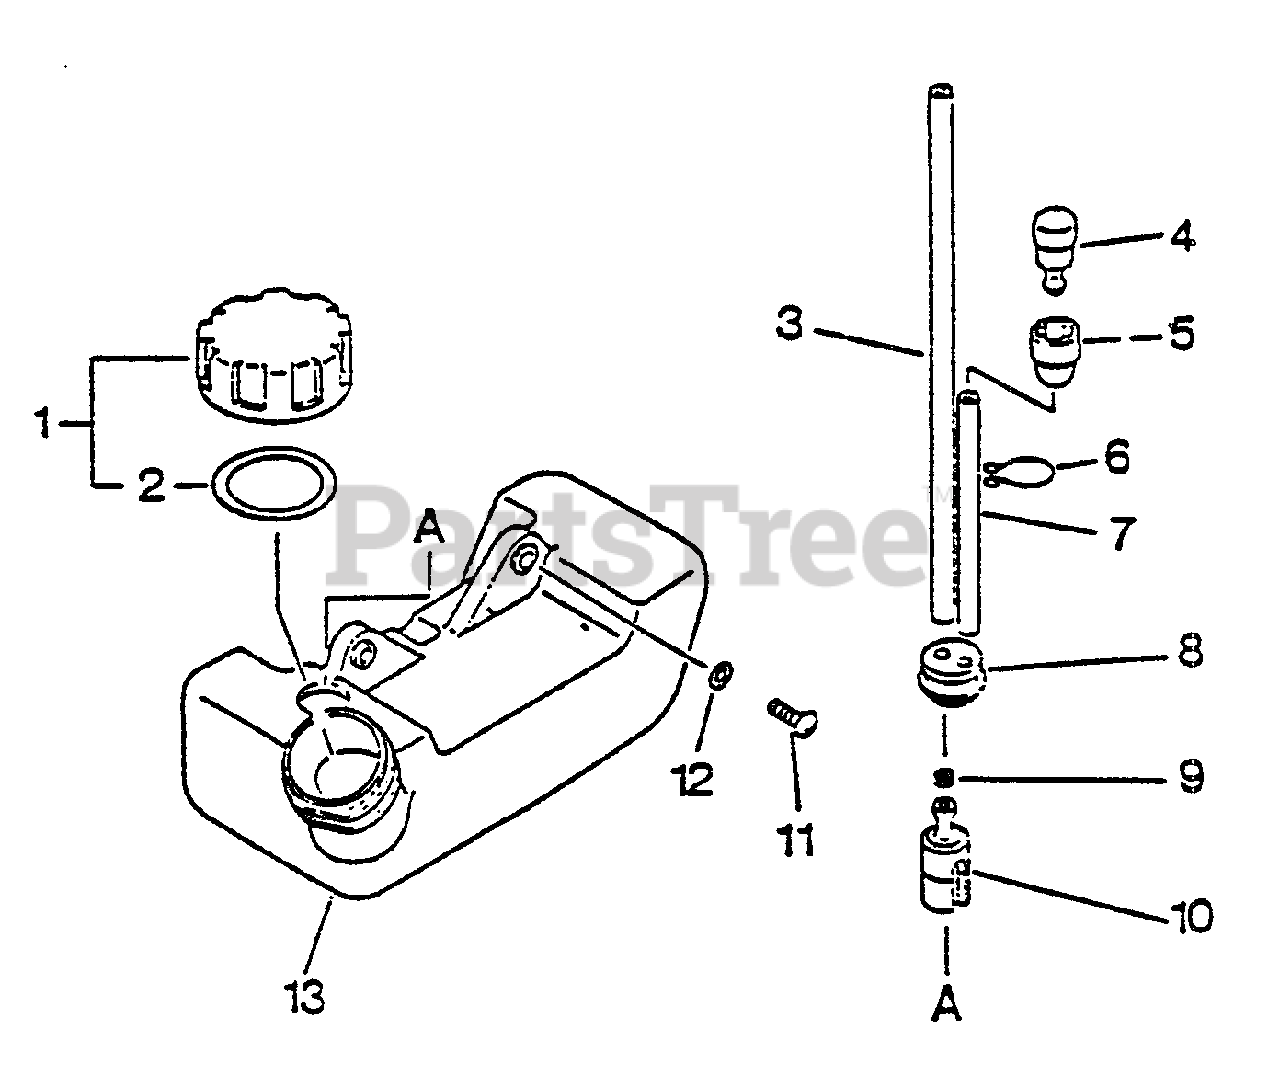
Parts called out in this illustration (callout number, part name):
1	CAP ASSY
2	GASKET, CAP
3	PIPE - 3X5X180 -- BLACK
4	VENT, FUEL TANK
5	COVER, VENT
7	PIPE - 3X6X70 -- CLEAR
8	GROMMET
9	CLIP - 6
10	FILTER, FUEL
11	SCREW - 5X16
12	WASHER - 5
13	TANK, FUEL
